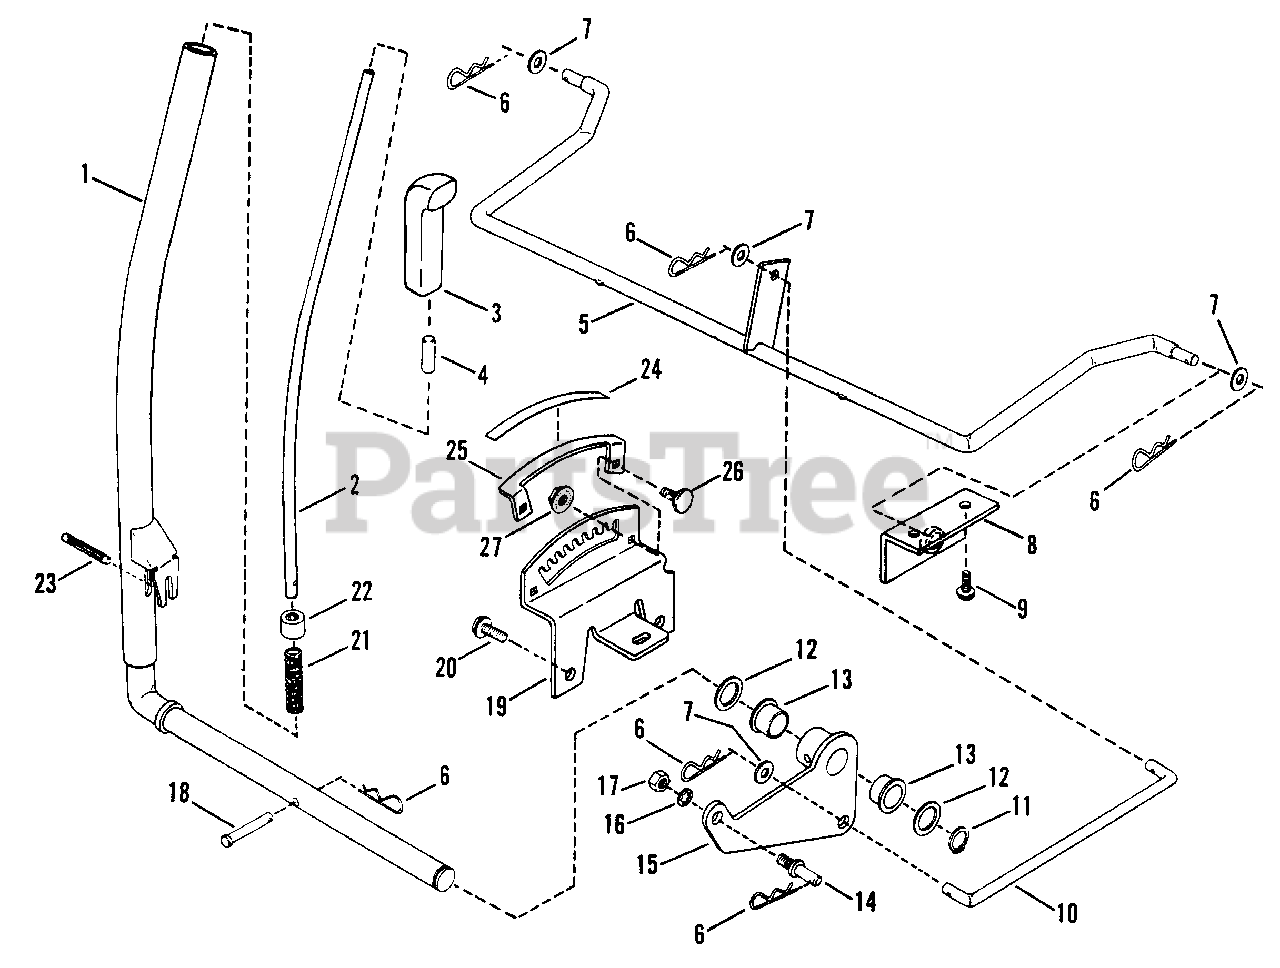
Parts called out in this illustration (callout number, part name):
1	ARM, Implement Lift Lever
2	ROD, Lift Lever
3	GRIP, Lift Lever
4	CAP, Lift Release
5	ARM, Rear Lift
6	PIN, Hair, 3/32 x 1-1/2"
7	WASHER, 3/8 SAE Flat
8	BRACKET, Hanger
9	SCREW, 5/16-18 x 5/8" H.W.H.S.T.
10	LIFT-ROD
11	RING, Retaining
12	WASHER, Lift Lever
13	BEARING, Lift Lever
14	STUD
15	PIVOT ASSEMBLY, Lift Lever
16	WASHER, 3/8 Int. Tooth Lock
17	NUT, 3/8-24 Hex
18	PIN, Clevis, 5/16 x 1-11/16"
19	QUADRANT, Lift Lever
20	SCREW, 5/16-18 x 5/8" Self-Tapping
21	SPRING, Lift Lever
22	PLUG, Lift Lever
23	GROOVE-PIN, 3/1 6 x 2"
24	DECAL, Cut Height
25	INDICATOR, Cut Height
26	BOLT, 1/4-20 x 5/8" Flt. Hd. Carr.
27	NUT, 1/4-20 Hex Flg. Lock
